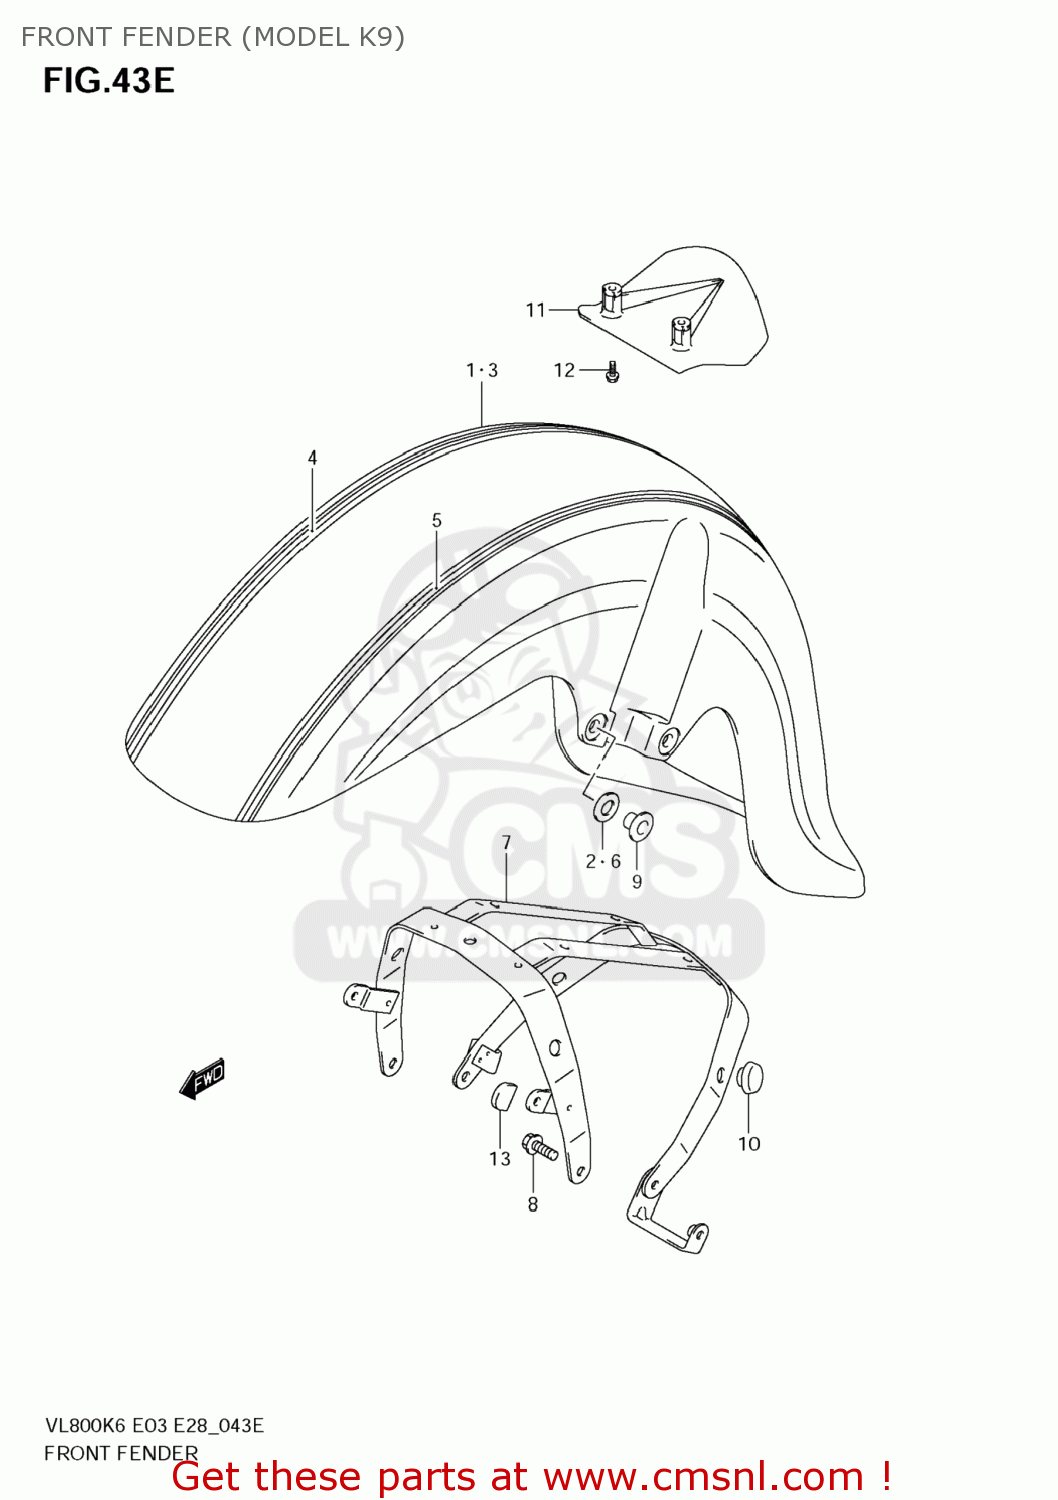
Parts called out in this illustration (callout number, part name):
1	FENDER COMP,FR
2	CUSHION,FR FENDER
3	FENDER COMP,FRO
4	TAPE SET,FR FENDER,R
5	TAPE SET,FR FENDER,L
6	CUSHION,FR FENDER
7	BRACE,FR FENDER
8	BOLT
9	WASHER,FR FENDER
10	CUSHION
11	WING,FR
12	BOLT(6X16)
13	CUSHION
